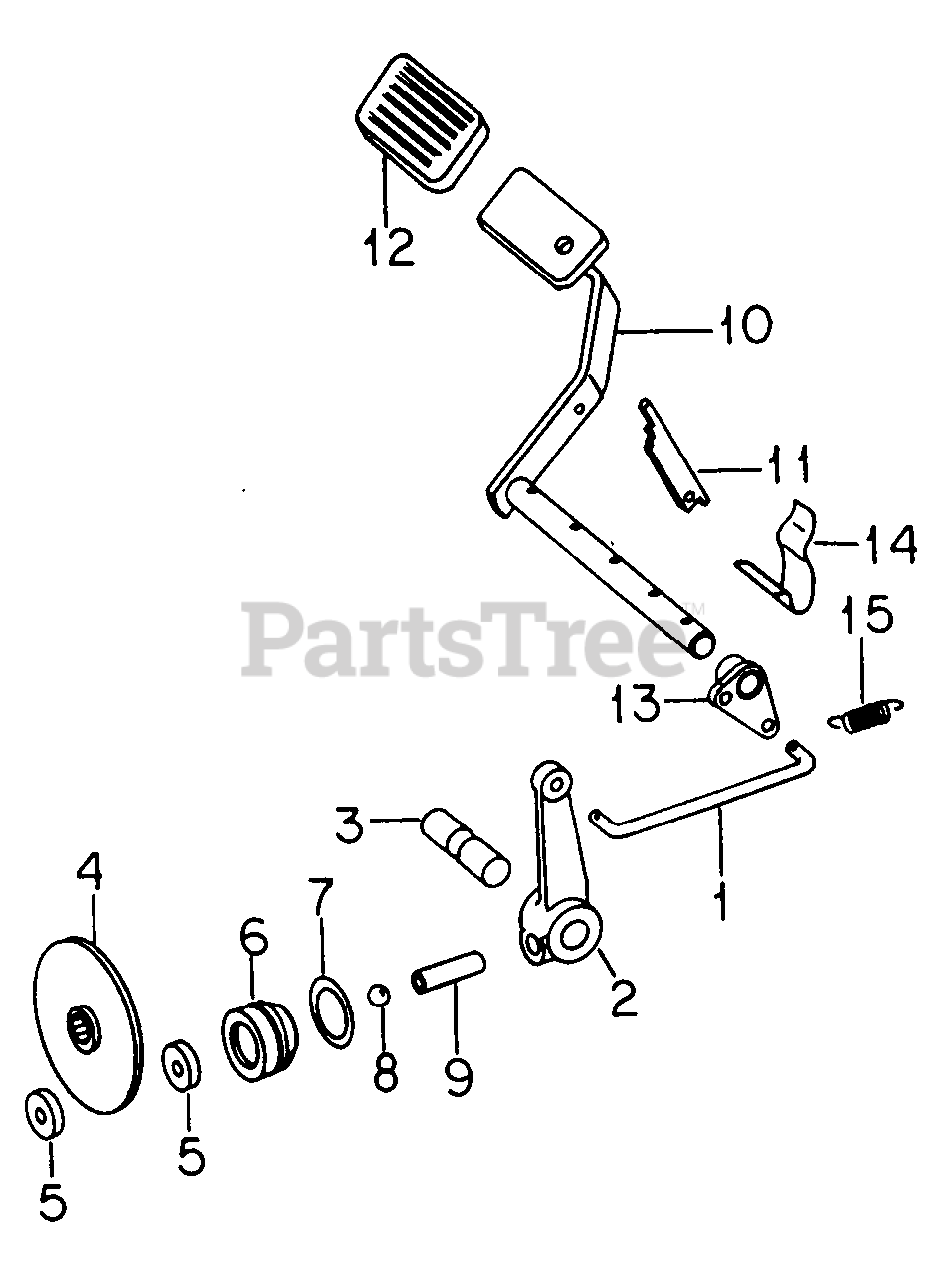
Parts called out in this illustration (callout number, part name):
1	Rod, Brake
2	Lever, Brake
3	Shaft, Brake Pivot
4	Disc Assy, Brake
5	Disc, Brake Lining
6	Retainer, Brake Lining
7	O-Ring, 1-3/16 X 3/32 Class 5
8	Ball, 9/16 Steel
9	Rod, Brake Push
10	Pedal Assy, Clutch
11	Ratchet
12	Pad, Pedal
15	Spring, Brake Pedal Return
